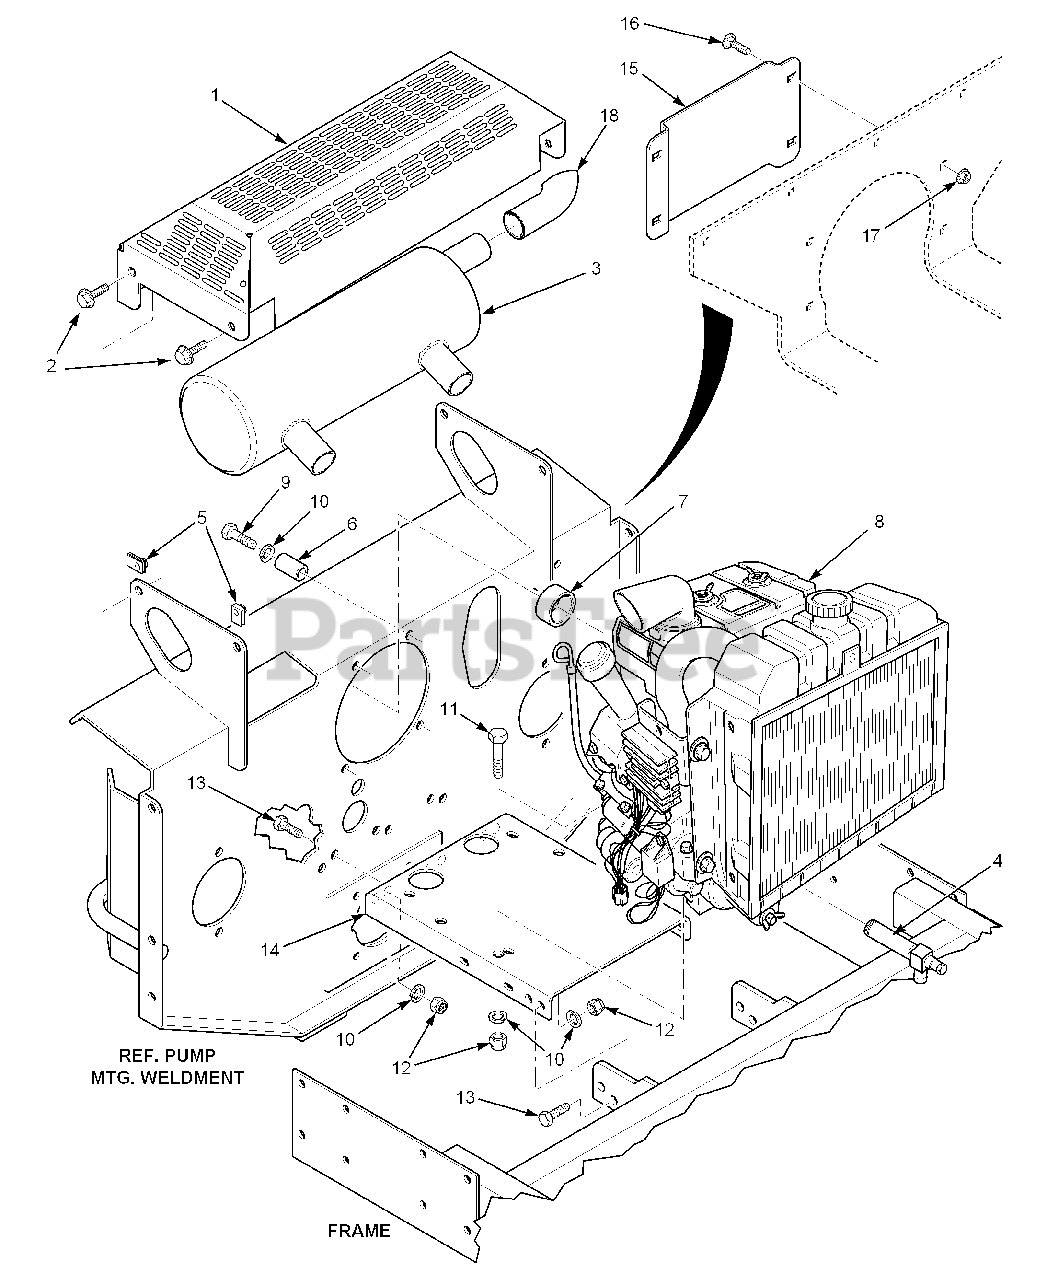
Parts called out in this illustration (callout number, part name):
1	Muffler Guard
2	Screw, Hex Serrated Flange 1/4-20 x 3/4"
3	Muffler
4	Extension, Oil Drain
5	U-Nut, 1/4-20
6	Spacer, Engine Bolt
7	Spacer, Engine
8	Engine, Kawasaki 22KA
9	Bolt, M8-1.25 x 25 Grade 8.8
10	Lockwasher, 3/8" Spring
11	Bolt, Hex Head 3/8-16 x 1-3/4"
12	Nut, Hex Elastic Stop 3/8-16
13	Bolt, Hex Head 3/8-16 x 1-1/4"
14	Plate, Engine Mounting
15	Rear Cover
16	Bolt, Carriage 5/16-18 x 3/4"
17	Nut, Hex Serrated Flange 5/16-18
18	Exhaust Elbow
